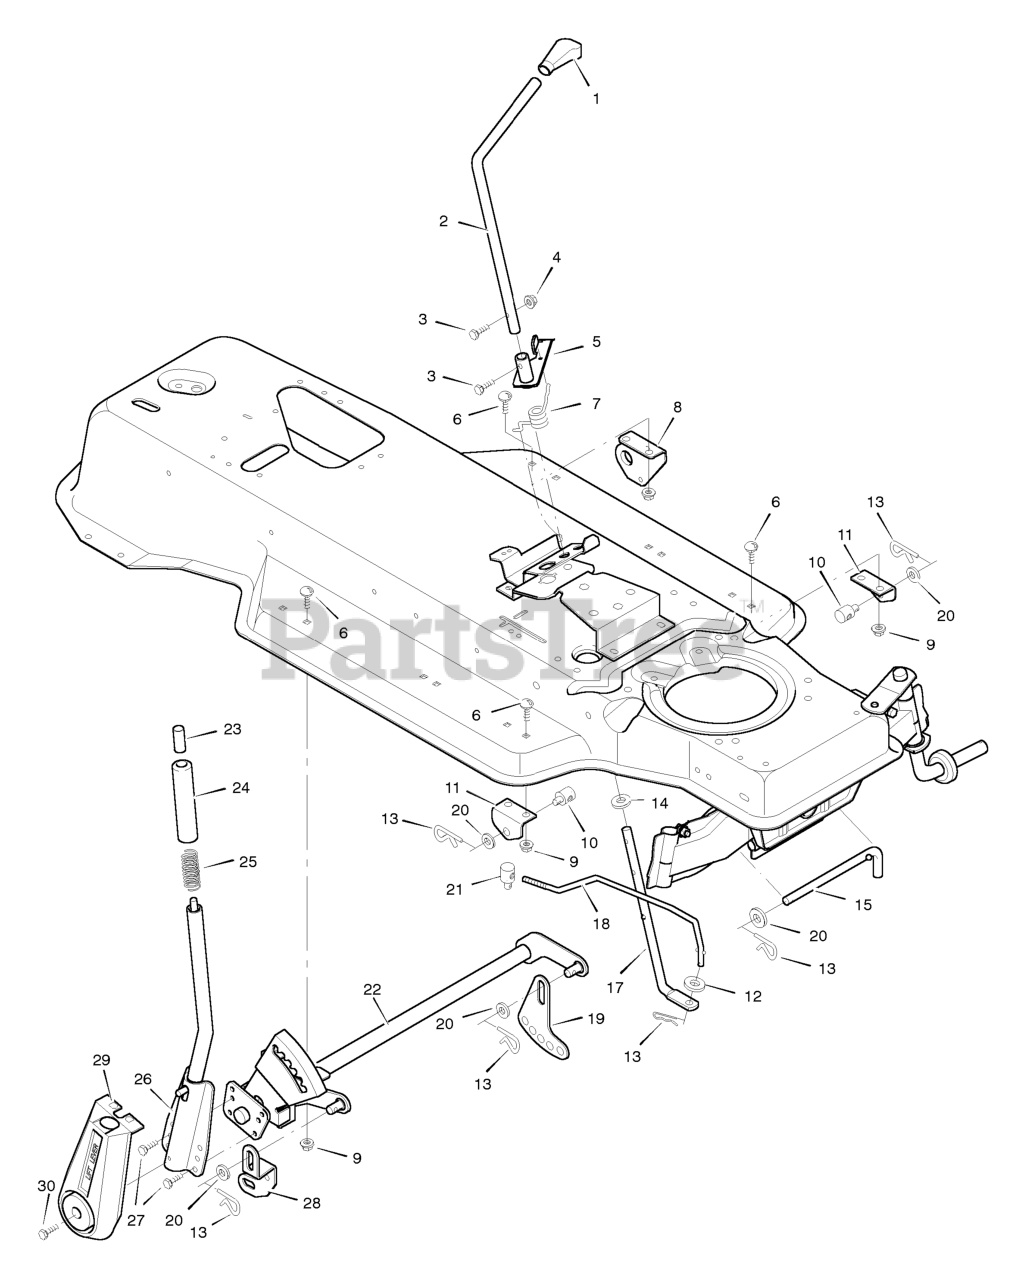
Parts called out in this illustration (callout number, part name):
1	Grip
2	Lever, Blade Control
3	Screw, Hex
4	Locknut, Hex
5	Lever Assembly, Switch
6	Bolt, Carriage
7	Spring, Torsion
8	Bracket, Adjuster Rod
9	Nut, Flange
10	NUT, Adjusting, 1/2-13
11	Bracket, Adjuster Rod
12	Washer
13	Pin, Hair
14	Washer
15	Pin, Pull
17	Lever, Lower Blade Control
18	Rod, Blade Control
19	Plate, Adjuster
21	Nut, Adjusting
22	Lifter Assembly
23	Button, Push
25	Spring, Compression
26	Handle Assembly
28	Link, Suspension
29	Cover, Lift Lever
